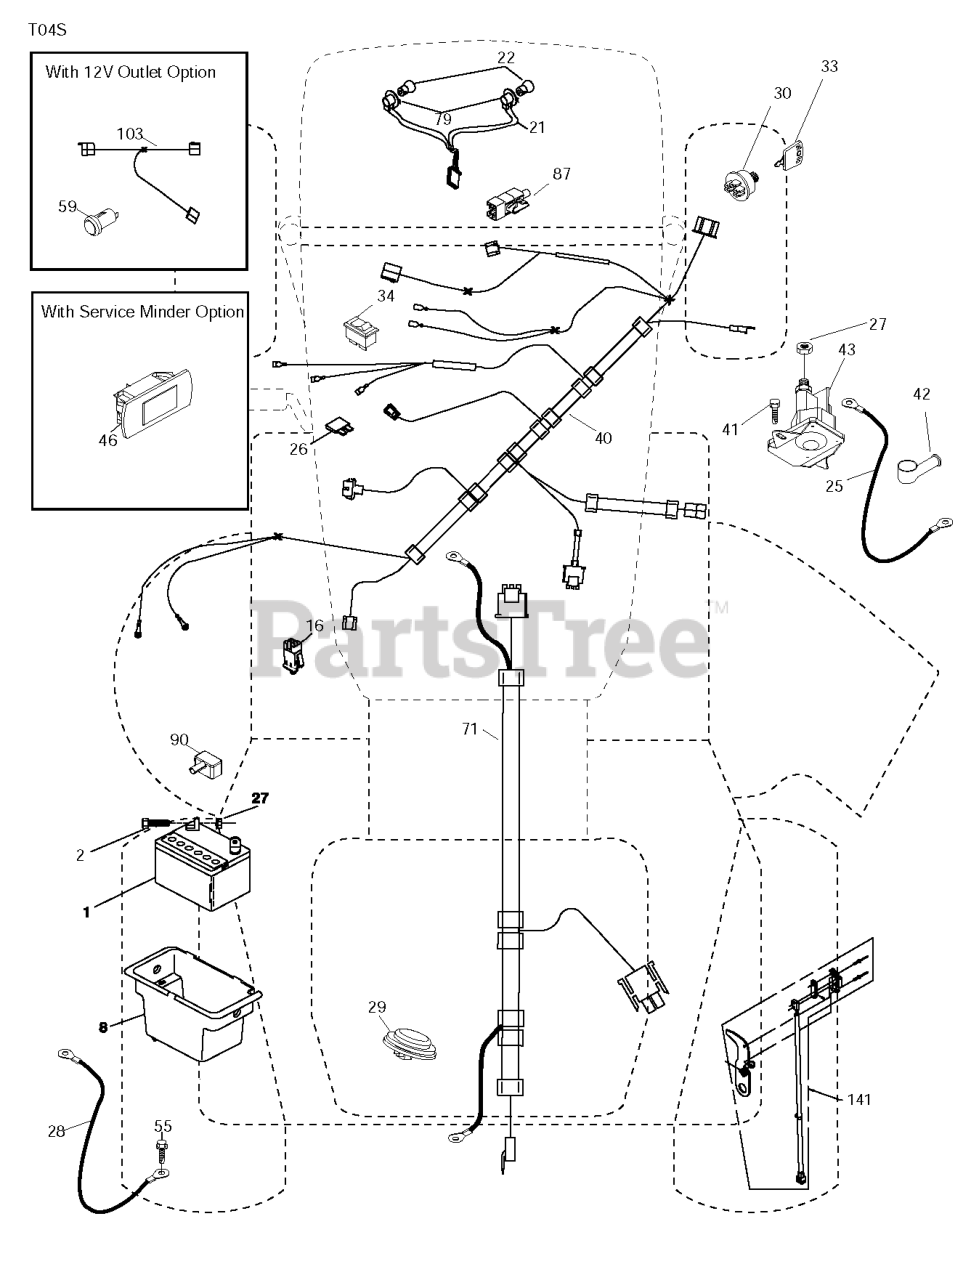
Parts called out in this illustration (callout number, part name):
1	REPL BY 532 12 38-99
2	BOLT.HEX.1/4.X.3/4.DICHROMATE
8	BOX.BATTERY.MNT.REAR.L
16	SWITCH INTERLOOK PUSH-IN
21	HARNESS.LIGHT W/4152J BULBS
25	CABLE.STARTER.6GA.BL/RED.14.
26	FUSE 20AMP
27	NUT
28	CABLE.BLACK.18"REAR.BA
29	SWITCH.SEAT.DELTA.OPC.
30	SWITCH.IGN.DELTA.W.LGH.ROS
33	KEY.CHAIN.BLISTER.PACK.GEN.INT
40	HARNESS IGN. DASH
41	SCREW
42	TERMINAL COVER
43	SOLENOID.W/BRASS.PLUNGER
55	SCREW 5/16"
71	HARNESS.IGN.CHASS.TEX.REAR.BAT
79	BULB HOLDER ASM.
87	SWITCH.INTRLCK.CLUTCH.
90	COVER, TERMINAL BATTERY
141	KIT T2.ROS 71677
